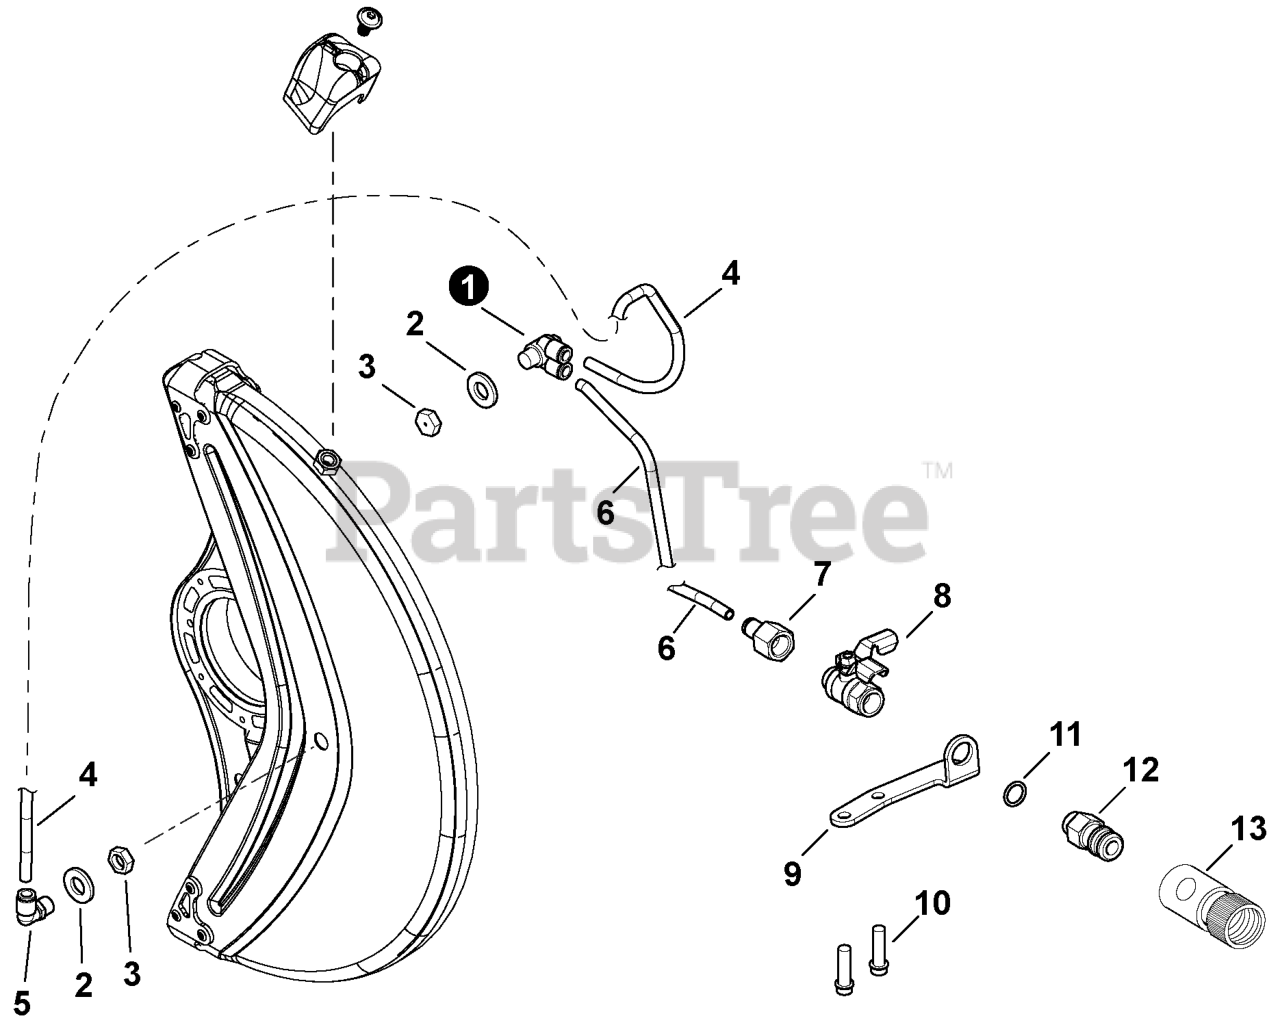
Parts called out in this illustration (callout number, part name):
1	CONNECTOR, PIPE
3	NUT, NOZZLE
5	CONNECTOR, PIPE
7	CONNECTOR, PIPE
8	PETCOCK
9	BRACKET
12	CONNECTOR, PIPE
13	COUPLER
